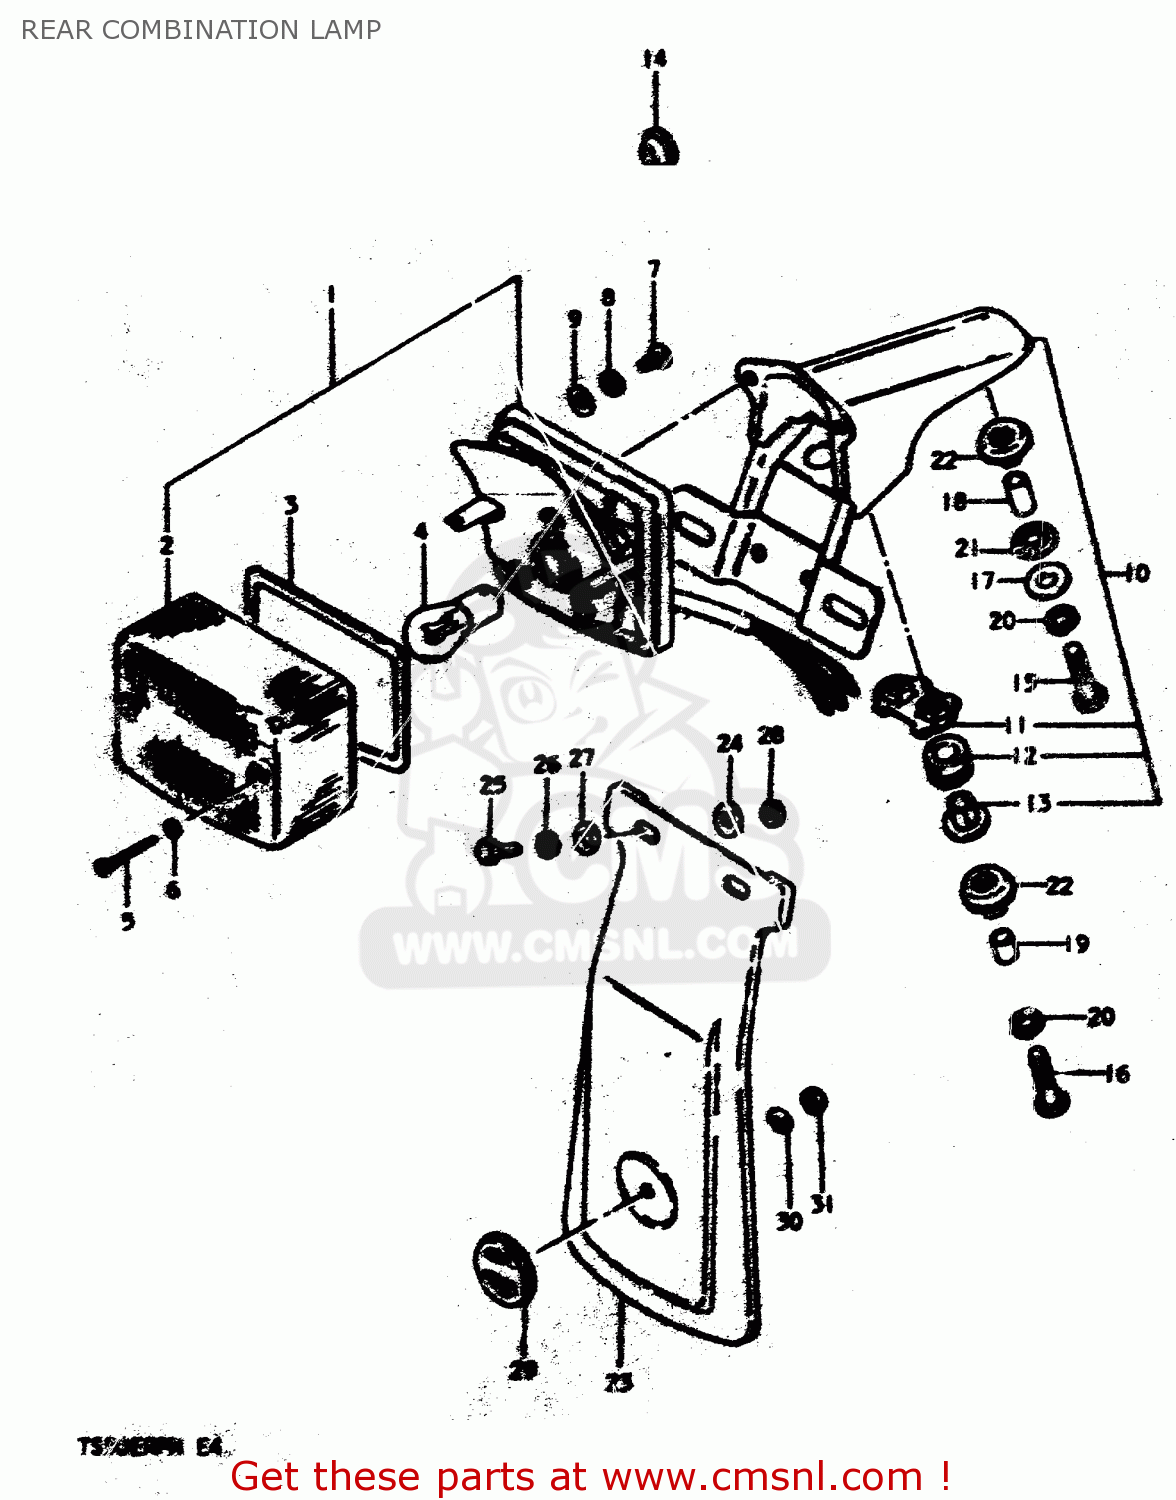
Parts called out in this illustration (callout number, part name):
1	LAMP UNIT, TAIL
2	LENS
3	GASKET (NAS)
4	BULB (6V,21/5W)
5	BOLT
6	GASKET (NAS)
7	SCREW
8	WASHER,LOCK
9	WASHER
10	BRACKET ASSY
11	PLATE
12	CUSHION
13	SPACER
14	GROMMET
15	BOLT
16	BOLT 6X40
17	WASHER (6.5X20X1.2)
18	SPACER
19	SPACER (6.8X10X11.5)
20	LOCK WASHER
21	CUSHION
22	CUSHION
23	MUD GUARD,REAR FENDER
24	WASHER
25	BOLT, UPPER
26	LOCK WASHER
27	WASHER
28	NUT
29	REFLECTOR,REFLEX
30	WASHER
31	NUT
